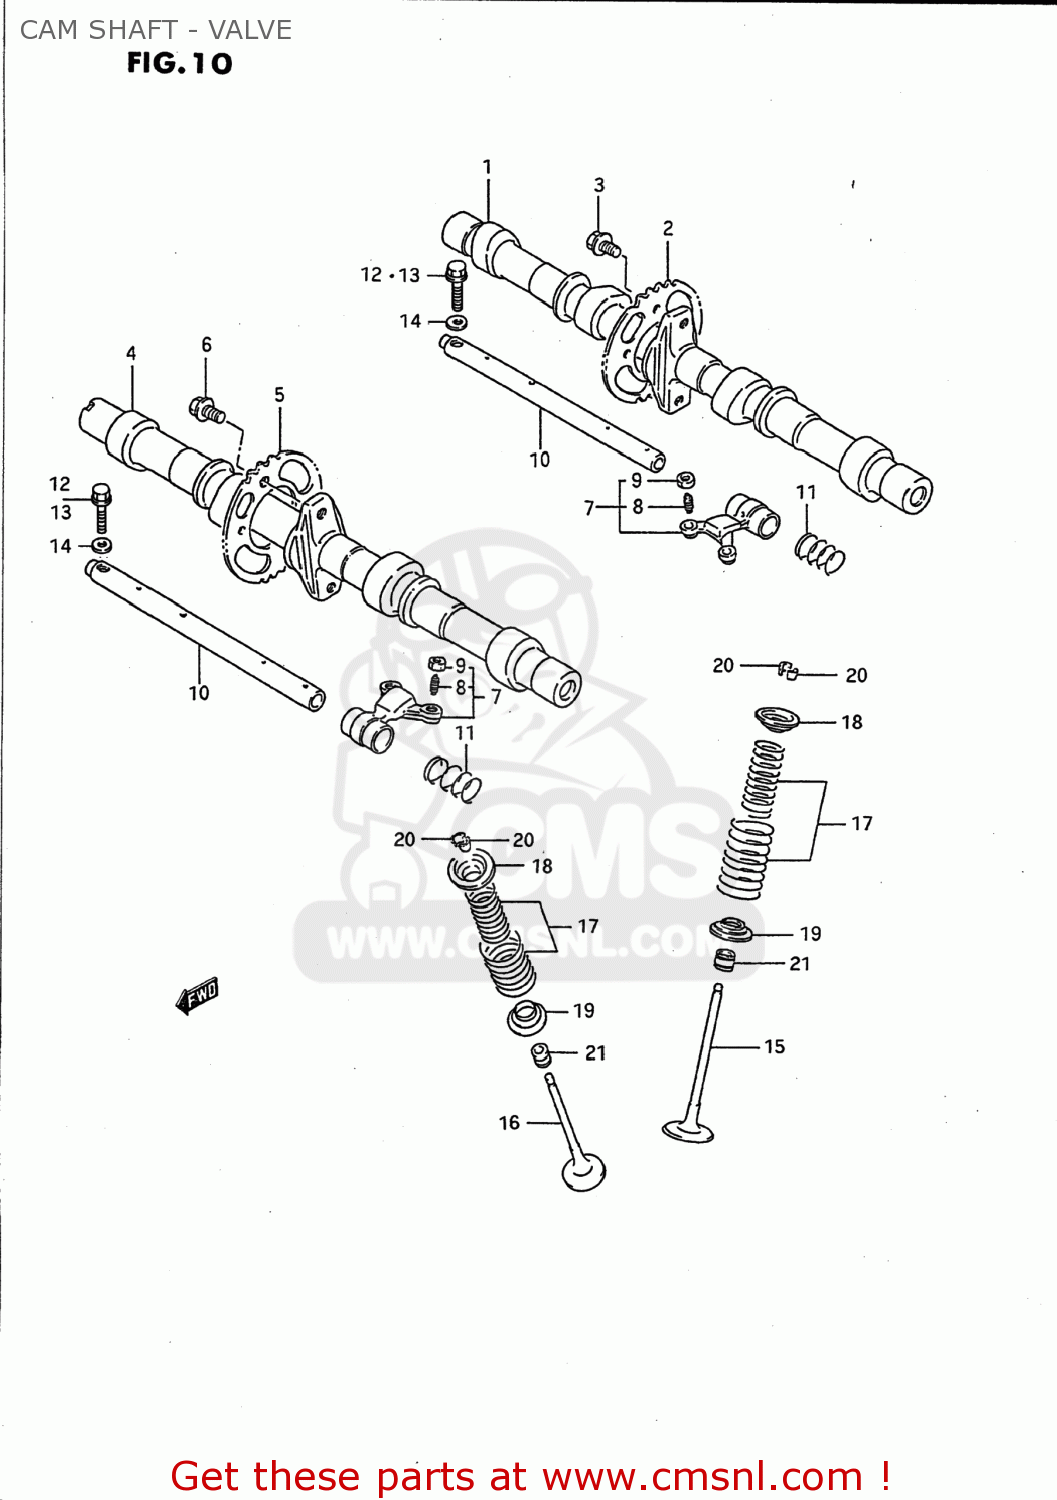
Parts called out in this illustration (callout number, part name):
1	CAMSHAFT,INTAKE
2	SPROCKET,CAMSHAFT
3	BOLT(7X11)
4	CAMSHAFT,EXHAUST
5	SPROCKET,CAMSHAFT
6	BOLT(7X11)
7	ARM,VALVE ROCKER
8	SCREW,TAPPET ADJUSTING
9	NUT,TAPPET ADJUSTING
10	SHAFT,VALVE ROCKER ARM
11	SPRING
12	BOLT
13	BOLT
14	WASHER
15	VALVE,INTAKE
16	VALVE,EXHAUST
17	SPRING SET,VALVE
18	RETAINER,VALVE SPRING
19	SEAT,VALVE SPRING
20	COTTER VALVE
21	SEAL,OIL(5X10X9.7)
